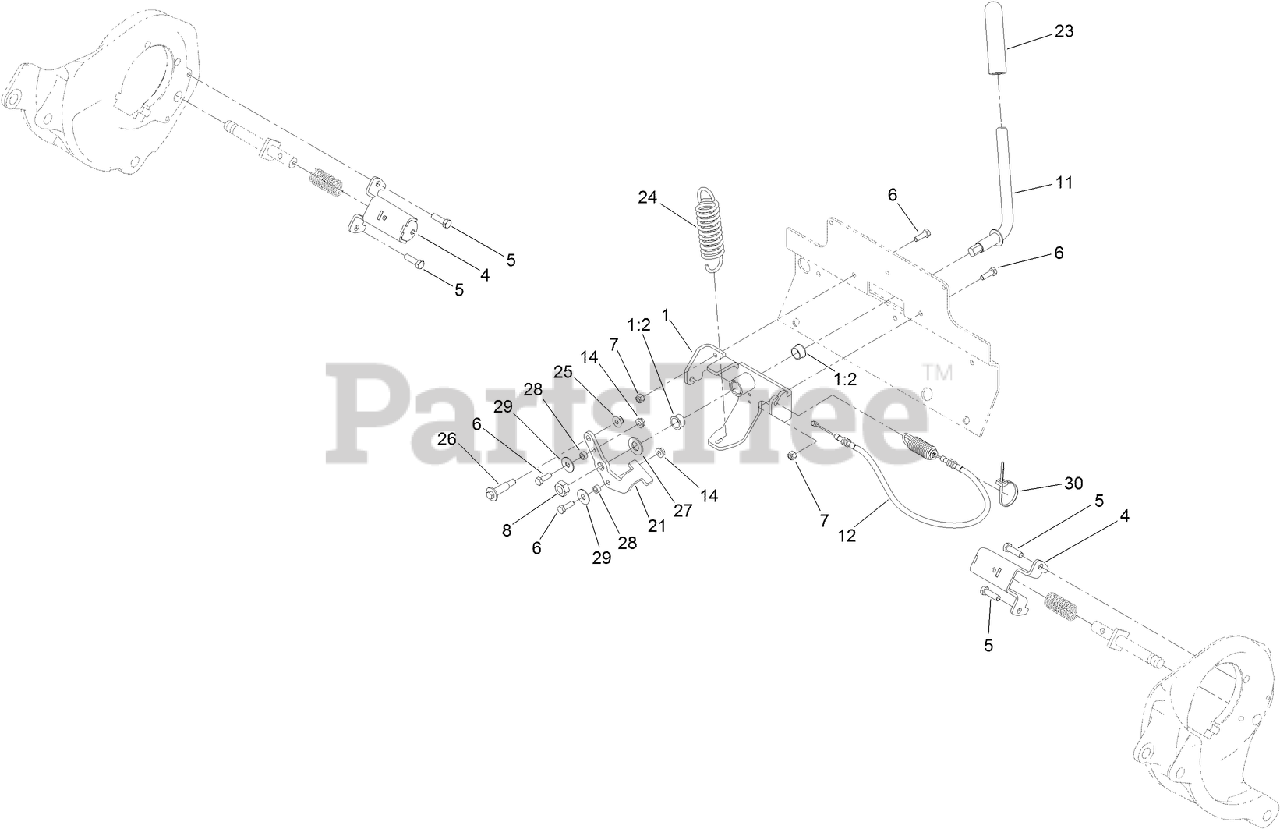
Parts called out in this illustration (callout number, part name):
1	BRACKET-BRAKE
1:2	BEARING-FLANGE
4	MOUNT-BRAKE
5	SCREW-HH
6	SCREW-HH
7	NUT-LOCK, NI
8	NUT-LOCK, NI
11	LEVER-BRAKE
12	CABLE-BRAKE
14	NUT-HF
21	PLATE-LINKAGE, BRAKE
23	GRIP-HANDLE
24	SPRING-EXT
25	NUT-HF, NI
26	BOLT-SHOULDER
27	WASHER-FLAT
28	SPACER-PIVOT, TILT
29	WASHER
30	TIE-CABLE
